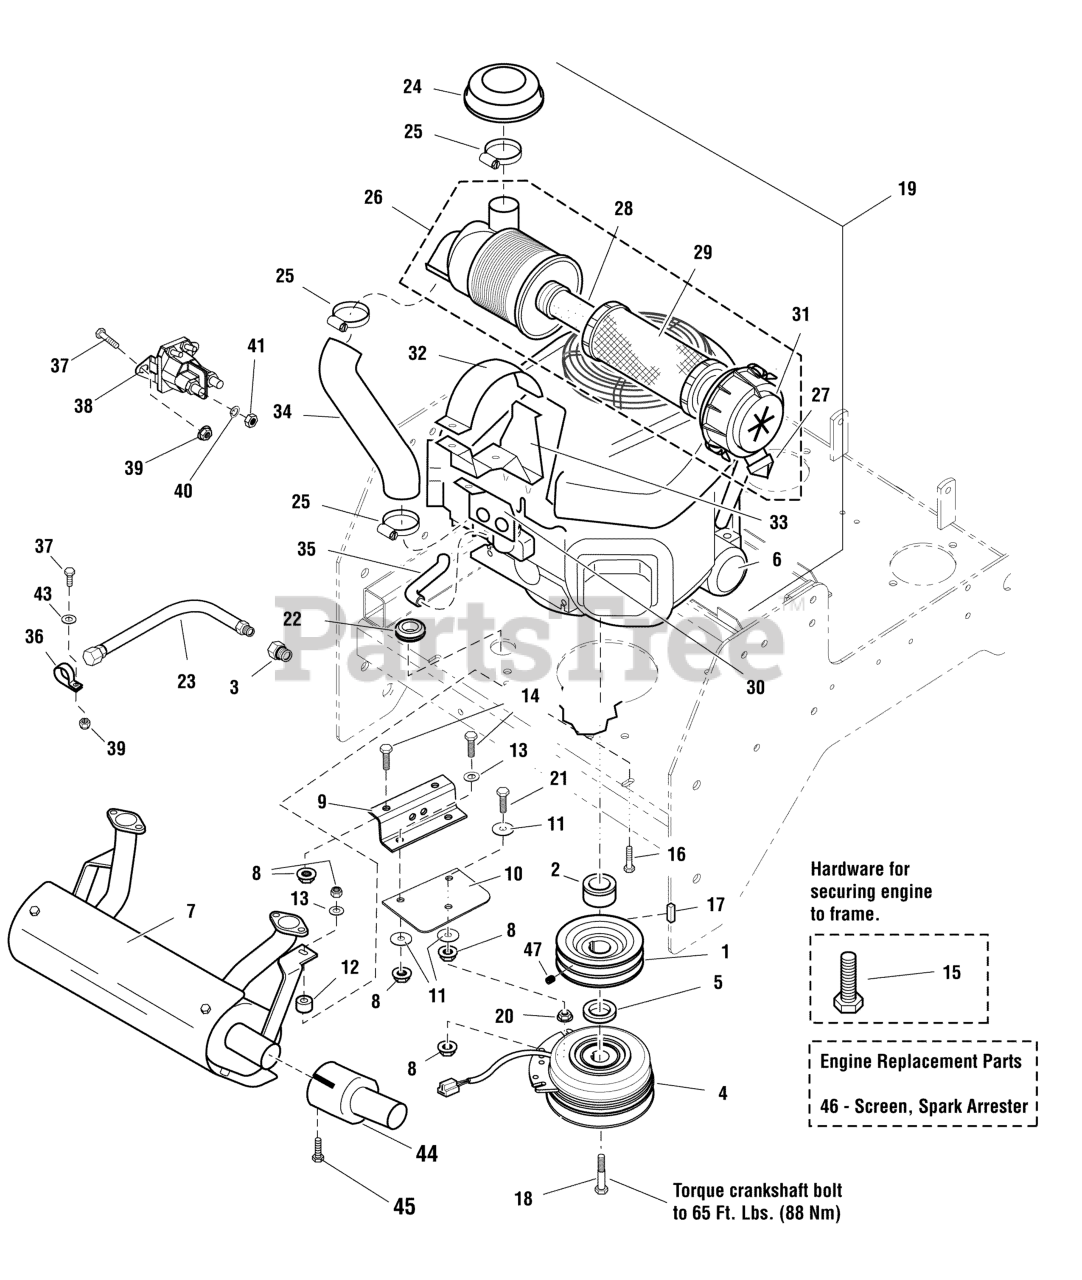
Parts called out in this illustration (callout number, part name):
1	PULLEY, CRANKSHAFT (DOUBLE A)
2	SPACER, 1.13 X 1.75 X 1.03
3	ADAPTER, OIL DRAIN
4	* CLUTCH, 5218-134, WARNER
5	SPACER, 1.13 X 1.75 X .38
6	OIL FILTER (49065-2078)
7	MUFFLER, 27HP KAWASAKI, 5" CAN
8	NUT, 5/16-18 HEX NYLOCK FLANGE
9	ANCHOR, CLUTCH - BLK
10	CLUTCH ANCHOR PAD
11	WASHER, .34 X 1.25 X 10 GA
12	SPACER, .39 X 1.00 X .80
13	WASHER, 5/16" SAE
14	BOLT, 5/16-18 X 1 GD5 YZ
15	BOLT, HEX FLG, SER GD5 3/8-16 X 1-1/4, PATCH
16	BOLT, 5/16-18 X 1-3/4 GD5 YZ
17	KEY, 1/4 SQ X 1
18	BOLT, CRANKSHAFT, 7/16"X2-1/2
19	ENGINE, 27HP, KAWASAKI
20	NUT, 5/16-18 HEX SERRATED FLANGE (LARGE)
21	BOLT, 5/16-18 X 2-1/4 TFL, GD5 YZ
22	GROMMET, 7/8
23	HOSE, OIL DRAIN
30	BRACKET PLATE, SUPPORT (SV)
36	CLAMP, VINYL INSULATED
37	BOLT, 1/4-20 X 3/4 GD5 YZ
38	SOLENOID-4 POLE 12 VOLT DC (TROMBETTA)
39	NUT, 1/4-20 HEX SERR. FLANGE
40	WASHER, Light Lock, 5/16
41	NUT, Hex Jam, 5/16-24
43	WASHER, 1/4 SAE
44	EXTENSION, TAILPIPE, 3" - BLACK
45	SCREW,SELF-TAP,#8-32 X 3/8,WASH HEX, CZ
47	SET SCREW, 5/16-18 X 3/8, KNURL, W/PATCH
